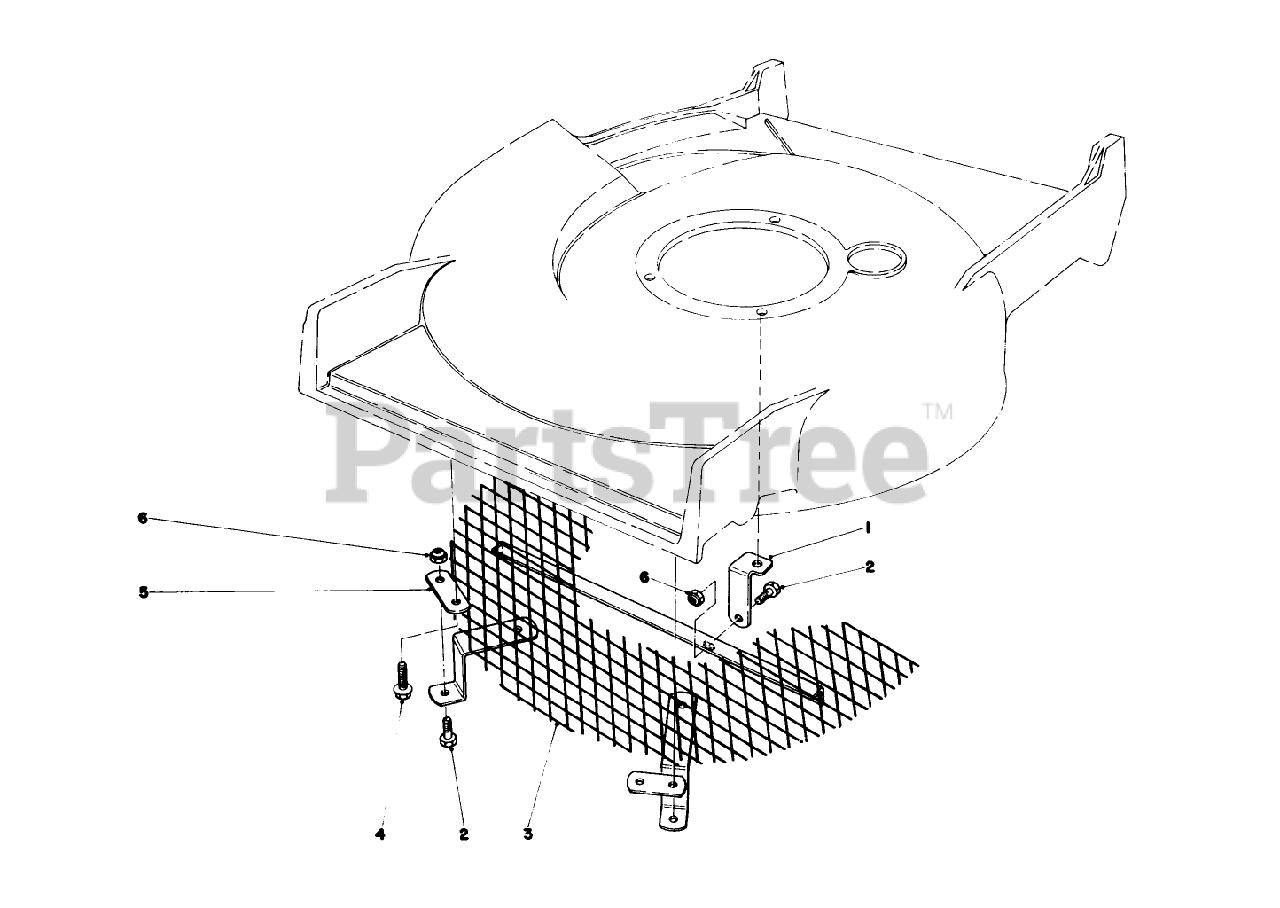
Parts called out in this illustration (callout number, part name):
2	SCREW-HH
4	SCREW-THD ROLL, HWH
6	NUT-LOCK, NI
